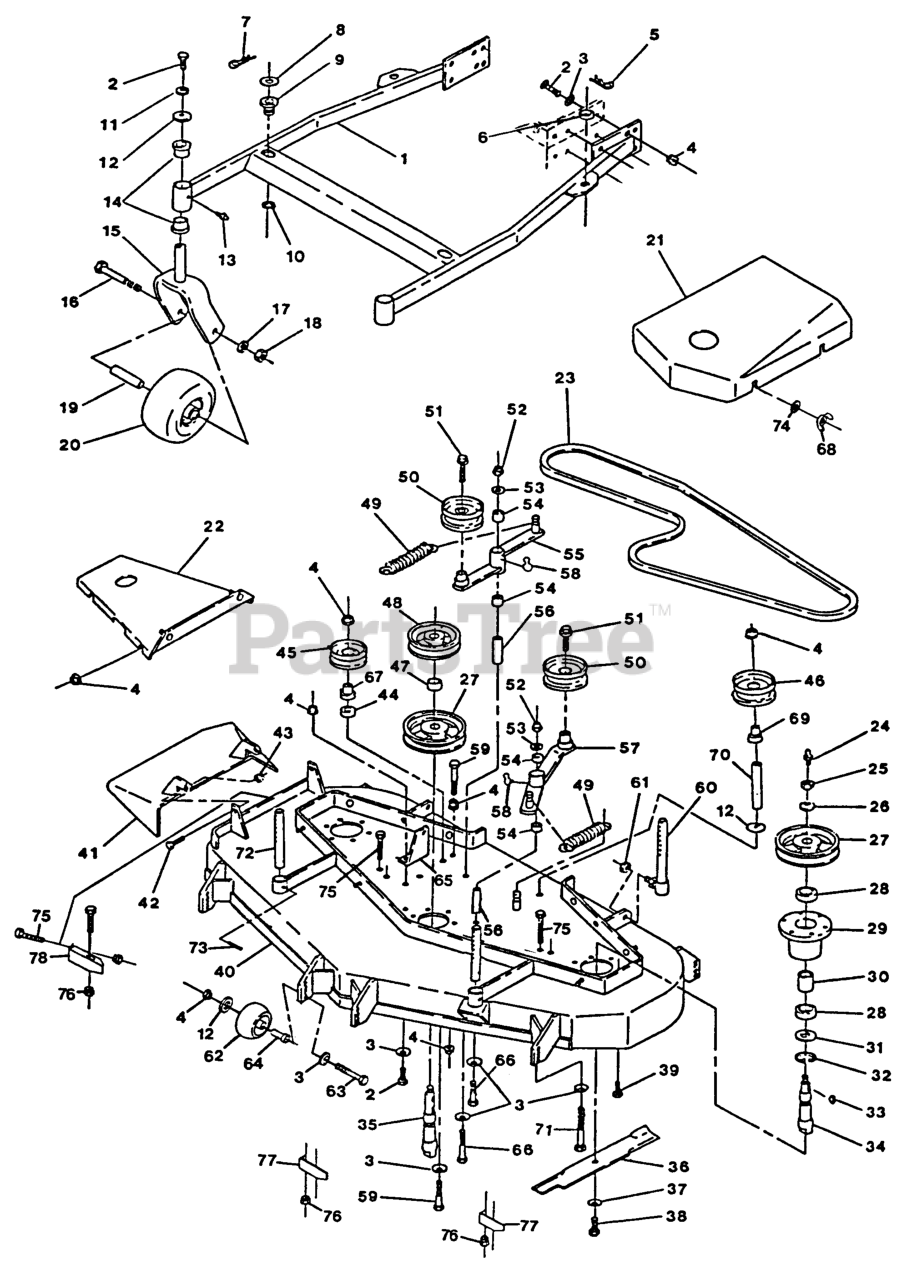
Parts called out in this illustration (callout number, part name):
5	PIN,HAIR COTTER
8	WASHER-FLAT
9	BUSHING-DECK
14	BEARING-FLANGED
23	BELT,BLADE DRIVE
26	WASHER-SPRING
27	SHEAVE,BLADE DRIVE
30	SPACER,BEARING
31	SEAL,MECHANICAL DUST
32	RING,SNAP WLDS N5000-244
34	SPINDLE-OUTER BLADE
35	SPINDLE-CENTER BLADE
37	WASHER-SPRING
39	SCRW,TPTTE HH
41	WLD,CHUTE DISCHARGE
46	PULLEY-IDLER
47	SPACER-TUBE
48	SHEAVE,MOWER DRIVE
49	SPRING-EXTENSION
50	IDLER,PULLEY
54	SLEEVE-BEARING
55	ASM,IDLER ARM
56	BUSHING-PIVOT, IDLER
57	ASM,IDLER ARM
62	ROLLER-SCALP, ANTI
64	BUSHING-ROLLER
65	BRACKET,SPRING ANCHOR
66	SCREW-HH
67	BUSHING-IDLER
68	NUT-WING
69	BUSHING,IDLER
70	SPACER-FENDER
72	ROD,DECK SUPPORT
78	WLD,BAFFLE DISCHARGE
